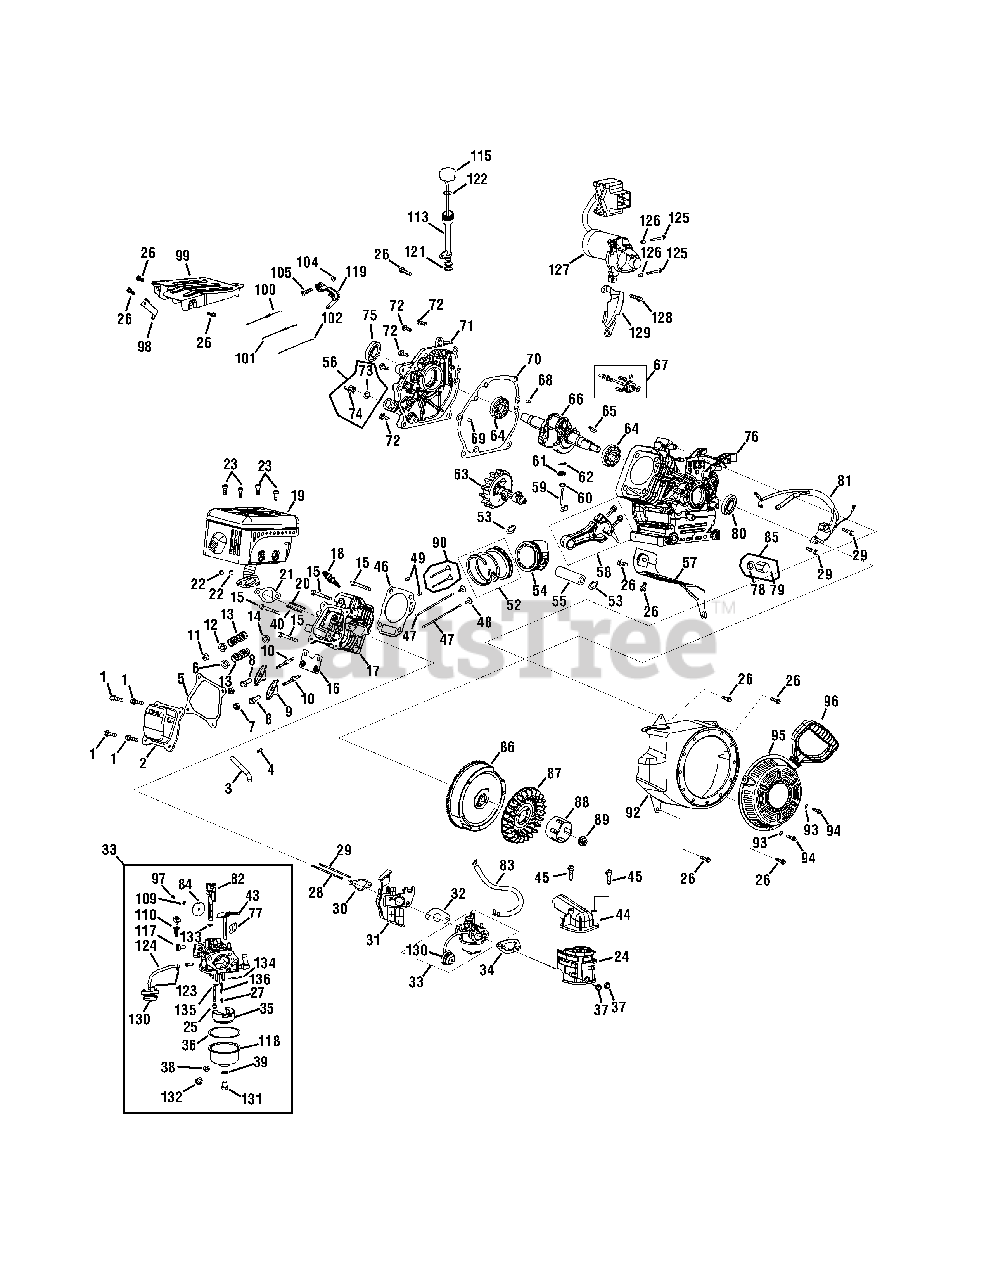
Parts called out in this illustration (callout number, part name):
2	Valve Cover
3	Breather Hose
4	Hose Clamp
5	Head Cover Gasket
6	Intake Valve Spring Seat
7	Pivot Locking Nut
8	Valve Adjusting Nut
9	Rocker Arm
10	Pivot Bolt
11	Exhaust Valve Adjuster
12	Exhaust Valve Spring Seat
13	Valve Spring
14	Intake Valve Seal
16	Push Rod Guide Plate
17	Cylinder Head - Complete
18	Spark Plug
19	Muffler Assembly
20	Stud
21	Muffler Gasket
23	Bolt
24	Heater Box Base
25	Main Jet
27	Needle Valve Spring
28	Stud, M6 x110
30	Carburetor Insulator Gasket
31	Carburetor Insulator Plate
32	Carburetor Gasket
33	Carburetor Assembly
34	Carburetor Gasket Plate
35	Float
36	Fuel Bowl Gasket
38	Fuel Drain Plug Gasket
39	Fuel Bowl Gasket
40	Muffler Stud Assembly
43	Choke Shaft
44	Heater Box
46	Cylinder Head Gasket
47	Push Rod Kit (incl. intake and exhaust rod)
48	Tappet
49	Dowel Pin
52	Piston Ring Set
53	Piston Pin Snap Ring
54	Piston
55	Piston Pin
56	Oil Fill Plug Assembly
57	Air Shield
58	Connecting Rod Assembly
59	Governor Arm Shaft
60	Washer
61	Governor Seal
62	Cotter Pin
63	Camshaft Assembly
64	Radial Ball Bearing
65	Flywheel Key
66	Crankshaft Assembly
67	Governor Gear/Shaft Assembly
68	Dowel Pin, 7 x 14
69	Dowel Pin, 9 x 14
70	Crankcase Cover Gasket
71	Cover Complete, Left Crankcase
71	Case Cover
72	Cover Bolt
73	O-Ring
74	Oil FIll Plug
74	Oil Fill Plug
75	Oil Seal
76	Crankcase
77	Choke Plate
78	Washer
79	Oil Drain Plug Washer
80	Oil Seal
81	Ignition Coil
82	Throttle Shaft
83	Fuel Line Kit (incl. clamps and fuel line)
84	Throttle Plate
85	Oil Drain Assembly, includes 78, 79
86	Flywheel
87	Cooling Fan
88	Starter Cup
89	Nut
90	Valve Kit (incl. intake and exhaust valve)
90	Valve Kit
92	Blower Housing
93	Washer
95	Recoil Starter
96	Starter Handle
97	Screw, M3×5
98	Governor Spring Bracket
99	Governor Shield
100	Governor Spring
101	Throttle Return Spring
102	Governor Rod
104	Nut
109	Lock Washer
110	Idle Jet Assembly
113	Dipstick Tube
115	Dipstick
117	Idle Speed Adjusting Screw
118	Fuel Bowl
119	Governor Arm Bracket
121	O-Ring
122	O-Ring
123	Hose Clamp
124	Primer Hose
126	Dowel Pin
127	Electric Starter
129	Blower Housing Shield
130	Primer
131	Bolt
132	Drain Bolt
133	Gasket, Throttle Plate
134	Float Pin
135	Emulsion Tube
136	Needle Valve
